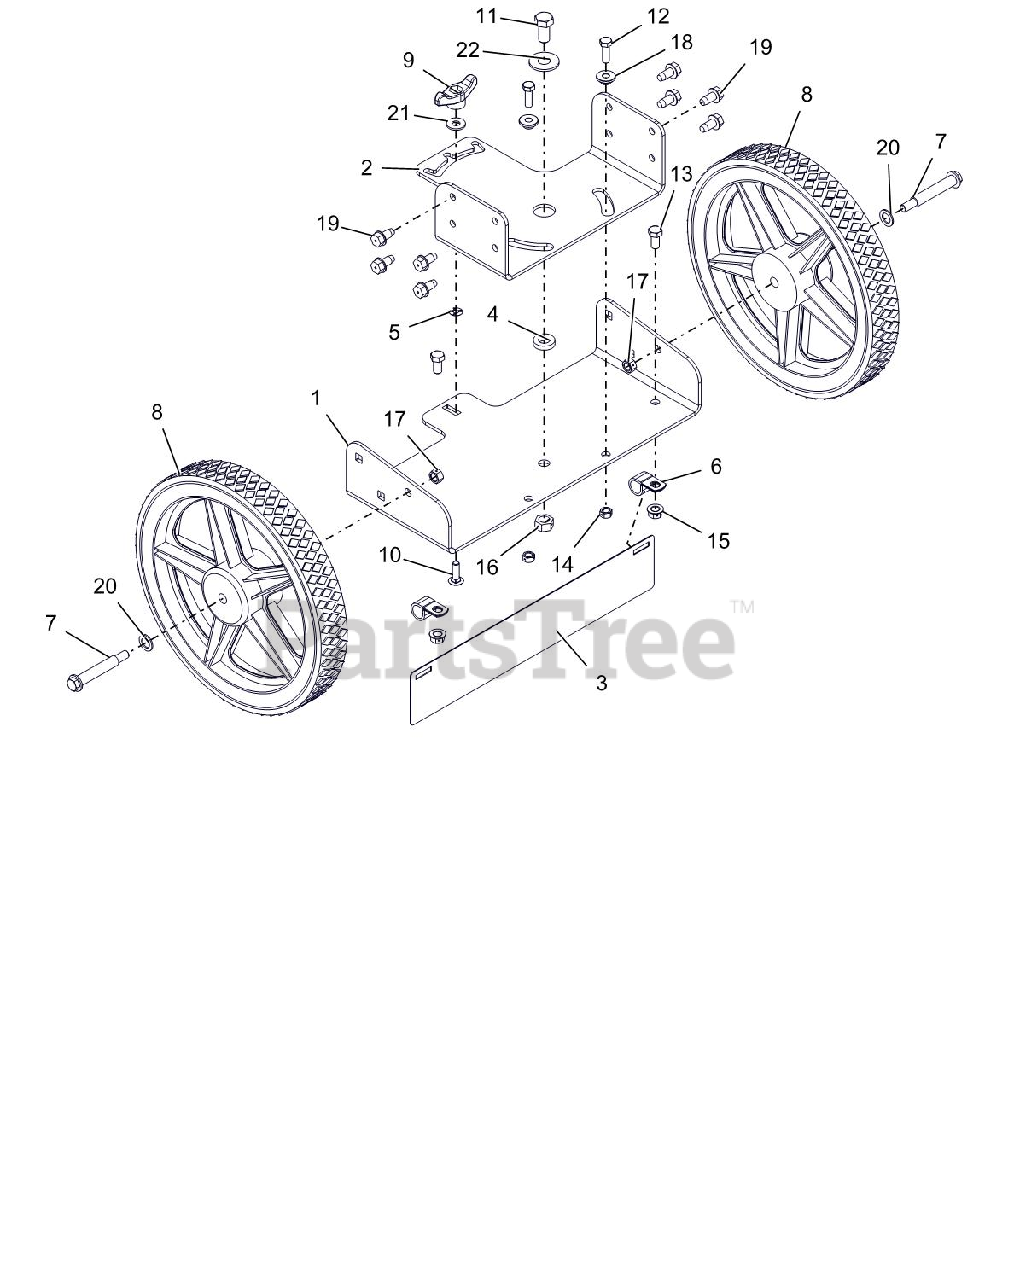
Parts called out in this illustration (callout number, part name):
1	FRAME, SWIVEL BOTTOM
2	FRAME, SWIVEL TOP
3	GUARD - REAR SWIVEL
4	SPACER .531 X 1.00 X .225
5	NUT-PUSH .312
6	CLAMP, CUSHIONED STEEL .75
7	BLT-SHLDR .38-16X2.50 HWH G5
8	WHEEL-12.000 X 1.750 X .500
9	KNOB,WING .31-18 UNC NYL/TALC
10	@BLT-RDHDSQNK .31-18X1.00 G5YZ
11	@BLT-HEX .50-13X1.00 GR5 YWZC
12	@BLT-HEX .31-18X1.00 GR5 YWZC
13	@BLT-HEX .38-16X.75 GR5 YWZC
14	@NUT-LK-CTR .31-18 YWZC
15	NUT-LK-CTR-FLG .38-16 YWZC
16	@NUT-LK-CTR .50-13 YWZC
17	@NUT-LK-CTR .38-16 YWZC
18	BSHG-FLG .32X.500X.344X.880
19	@SCR-TAP .38-16X.75 HWH TR YWZ
20	WSHR-FL-STL .52X.827X.062 YWZC
21	@WSHR-FL-STL.38X.875X.083 YWZC
22	@WSHR-FL-STL.563X1.38X.109YWZC
